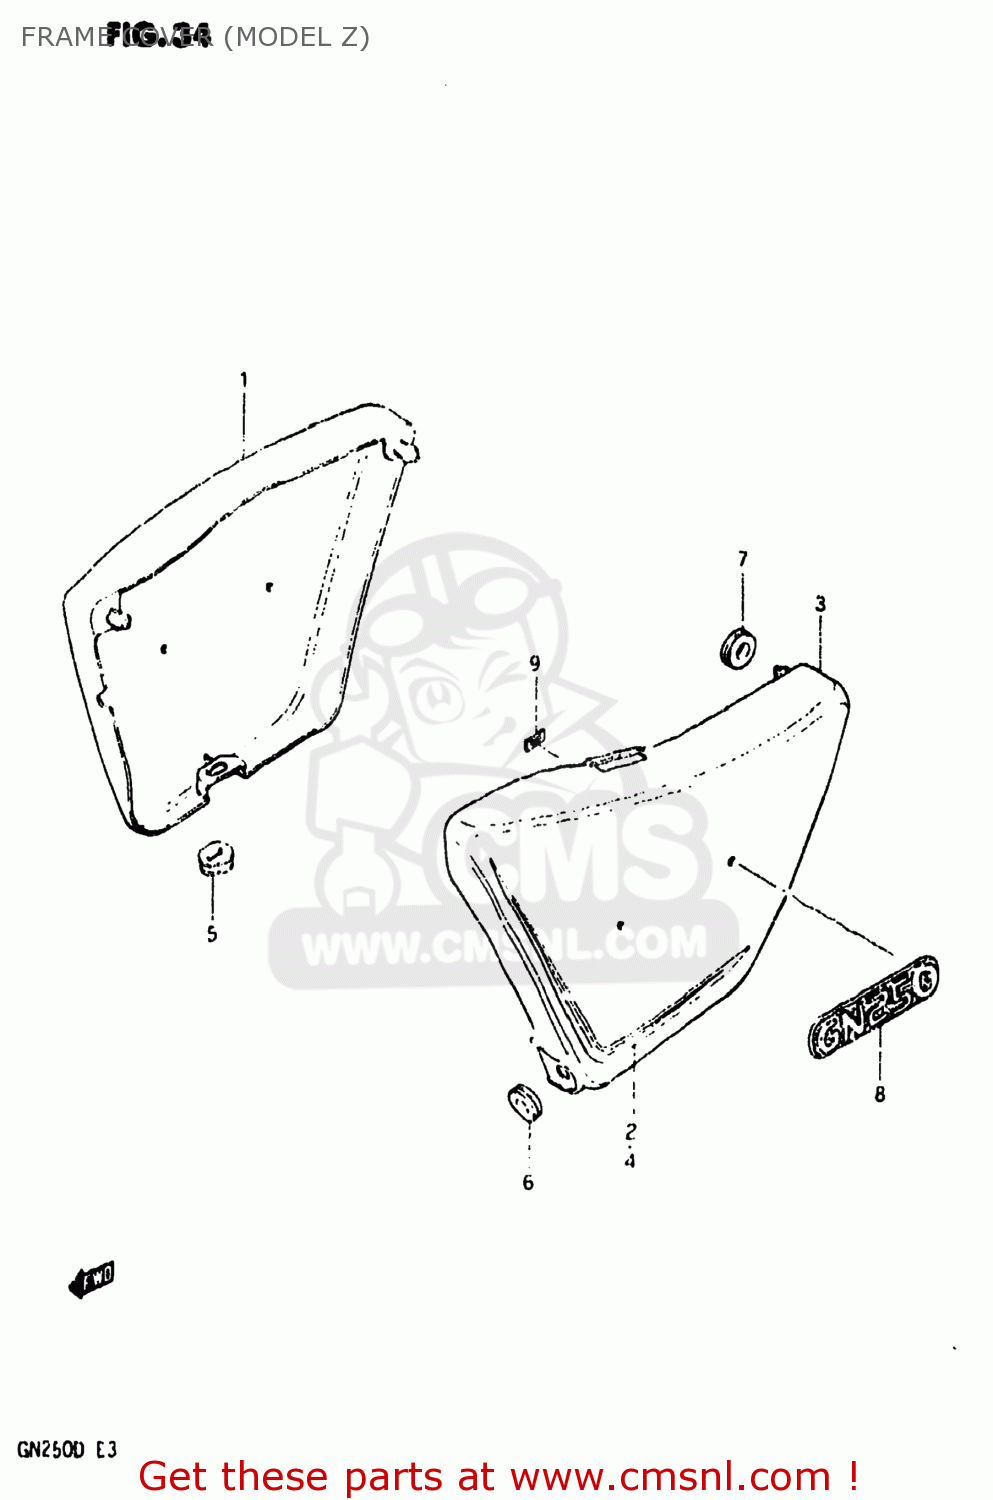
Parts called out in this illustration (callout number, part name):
1	COVER,FRAME,RIGHT
2	TAPE,FRAME COVER,RIGHT
3	COVER,FRAME,LEFT
4	TAPE,FRAME COVER,LEFT
5	CUSHION
6	CUSHION
7	CUSHION
8	EMBLEM,GN250
9	NUT
